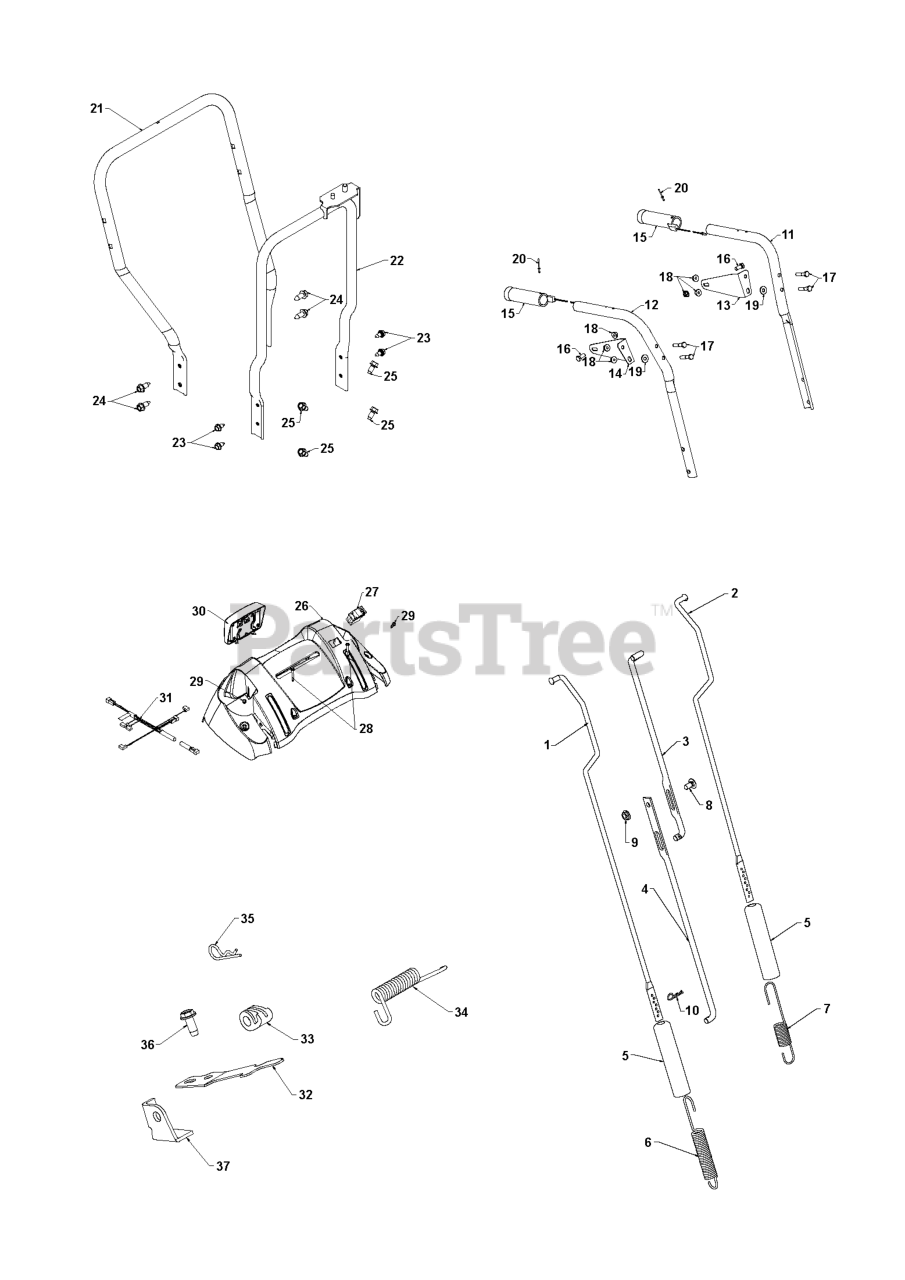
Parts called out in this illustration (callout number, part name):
1	ROD.IMPELLER
2	ROD.TRACTION
3	ROD.SHIFTER.TOP.HYD
4	ROD, LOWER, SPEED CONTROL
5	SLEEVE, SPRING
6	SPRING.CONTROL.ROD.SNOW
7	SPRING.TRACTION.ROD.SNOW
8	BOLT
9	NUT.FLANGE.5/16
10	SPRING RETAINER
11	TUBE.HANDLE.PLOW.LH.GREY
12	TUBE.HANDLE.PLOW.RH.GREY
13	BRACKET.PANEL.LH.
14	BRACKET.PANEL.RH.
15	GRIP.HANDLE.HEATED
16	BOLT.FIN.HEX.5/16-18X3/4
17	HEX BOLT
18	NUT.LOCK.5/16-18
19	WASHER.20X8.5
20	RIVET.POP.1/8X
21	HANDLE.LOWER.CHAIN.SNOW.GREY
22	SUPPORT.WELDMENT.ROTATOR.BLACK
23	BOLT.5/16HEX.WHS.HD
24	SCREW 3/8-16X1
25	SCREW, 3/8-16X3/4
26	PANEL.CONSOLE.
27	SWITCH.HEATED.GRIP
28	SCREW, HEX HD TAPPING #10-24 1
29	SCREW, HEX HEAD, TAPPING
30	HEADLIGHT.LED.DUAL STAGE.GREY
31	HARNESS.WIRE.FLOOD/LED.HEAT.
32	SPRING.INTERLOCK
33	CAM.INTERLOCK.RELEASE
34	SPRING.TORSION.LEVER
35	SPRING RETAINER
36	SCREW 14-20 X 5/8
37	STOP.INTERTLOCK
